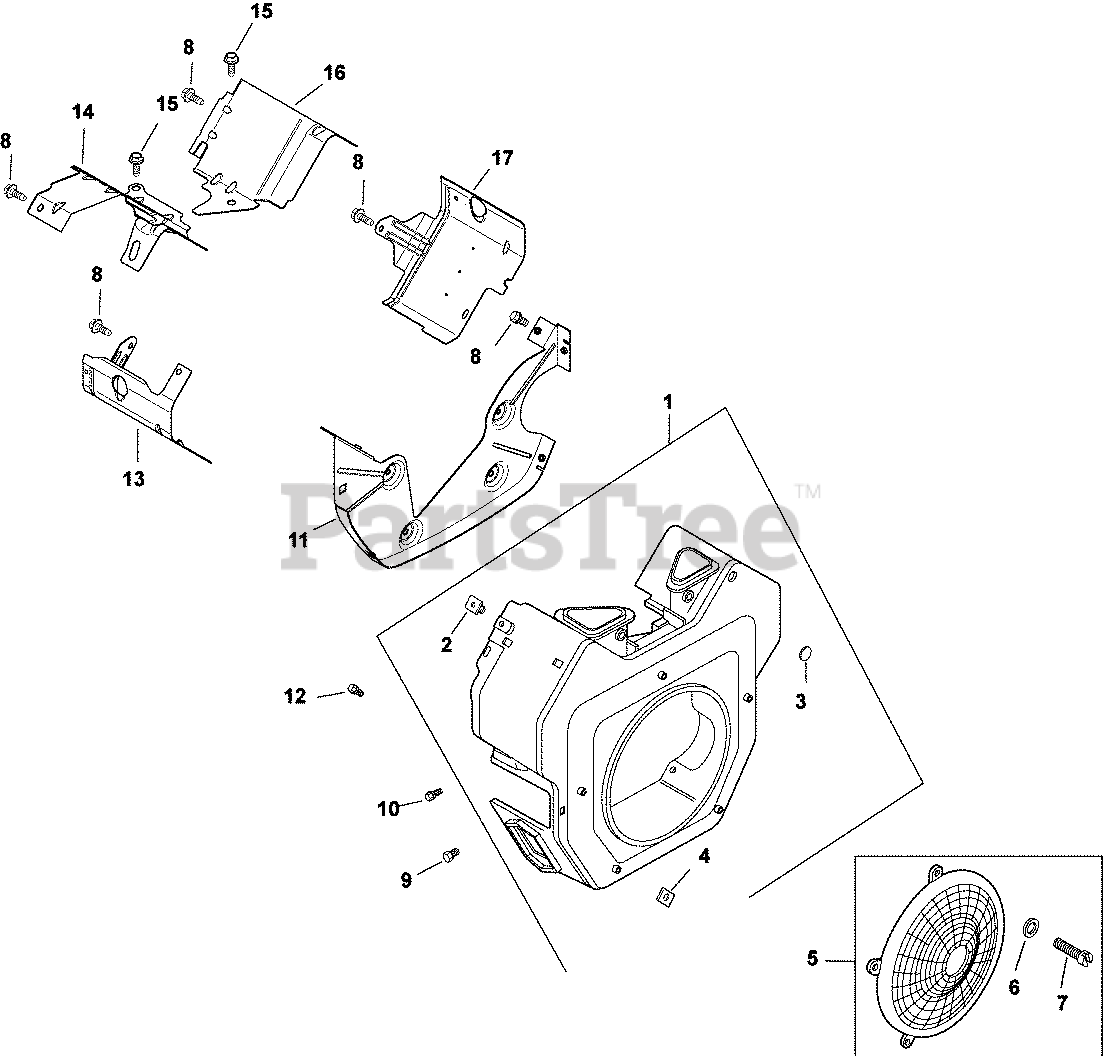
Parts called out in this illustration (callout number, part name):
1	KIT, BLOWER HOUSING ASSY-(#24027492S)
2	NUT, PLASTIC
3	PLUG, BUTTON 9/16
4	NUT, PLASTIC (KM)-USE 25 100 37-S
5	KIT, FIXED GUARD
6	WASHER, FLAT 7/32"
7	SCREW, LBD SCKT PAN M5X0.8X10
8	SCREW,FLG THD FRM M6X1.0X16-(#25086397S)
9	SCREW, HVY FLG M5X.8X16
10	SCREW,FLG THD FRM M5X0.8X16-(#25086398S)
11	PLATE, BACKING-USE 24 146 59-S
12	SCREW, FLG THD FRM M5X.8X20-(#25086399S)
13	BAFFLE,VALLEY #2SIDE(KM)-USE 24 063 88-S
14	BAFFLE, VALLEY #2 SIDE-USE 24 063 94-S
15	SCREW, FLG THD FRM M5X.8X10
16	BAFFLE, VALLEY (CH)-USE 24 063 93-S
17	BAFFLE, RIGHT BARREL-USE 24 063 85-S
